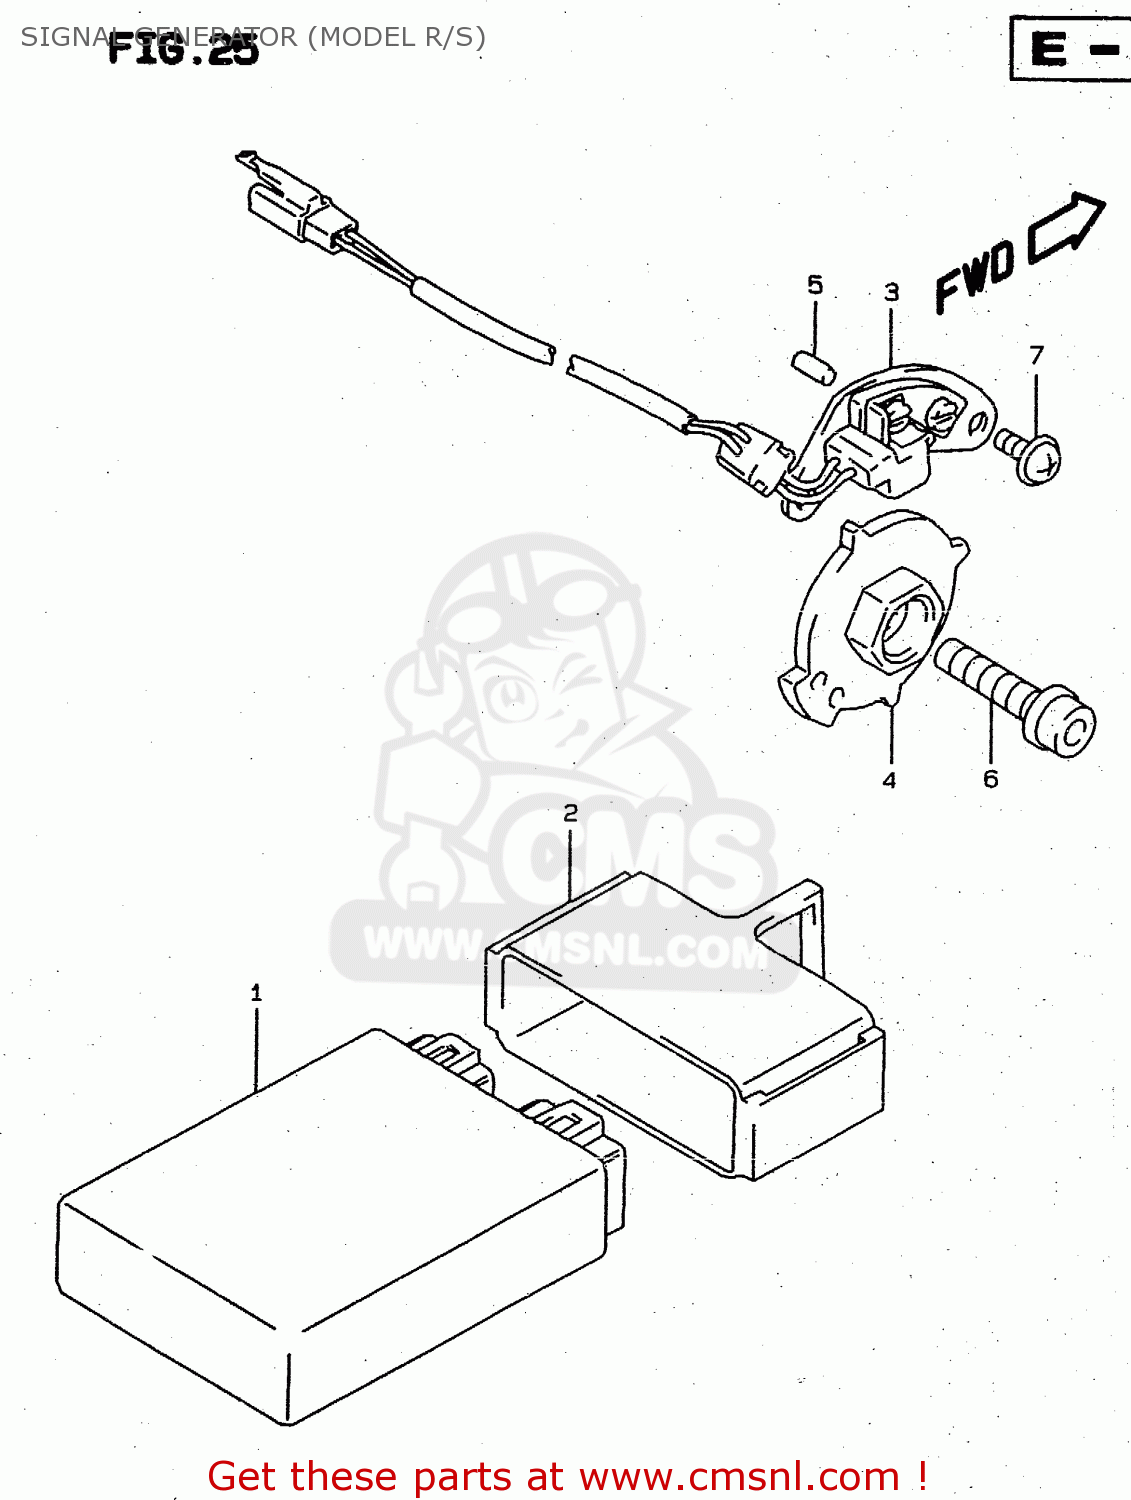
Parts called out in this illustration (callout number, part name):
1	IGNITOR ASSY
2	CUSHION,IGNITOR
3	STARTER,SIGNAL GENERATOR
4	ROTOR,SIGNAL GENERATOR
5	PIN
6	BOLT
7	SCREW
